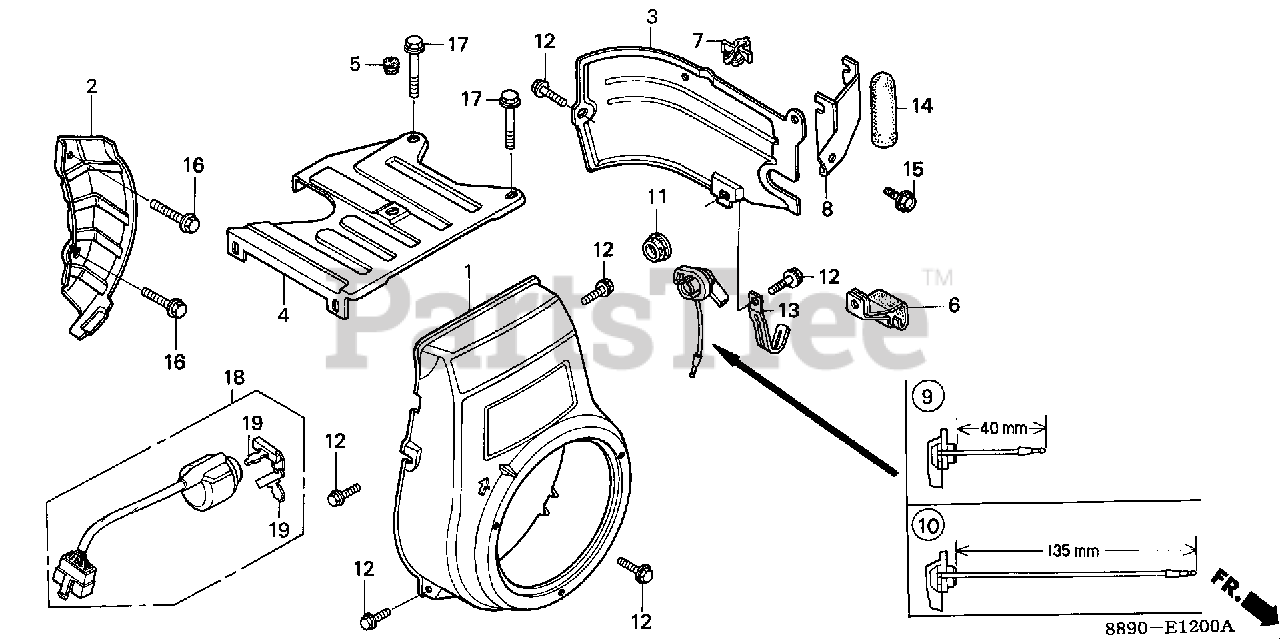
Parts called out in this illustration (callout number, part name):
1	COVER, FAN *R280* (POWER RED)
2	PLATE, SIDE
4	COVER, TOP
5	GROMMET, TOP COVER
7	CLIP, IGNITION WIRE (8MM)
10	SWITCH ASSY., ENGINE STOP
12	BOLT, FLANGE (6X12) (CT200)
13	CLIP, WIRE HARNESS
16	BOLT, FLANGE (8X20)
18	SWITCH ASSY., COMBINATION
18	SWITCH ASSY., COMBINATION (NOT AVAILABLE)
19	KEY (HONDALOCK)
